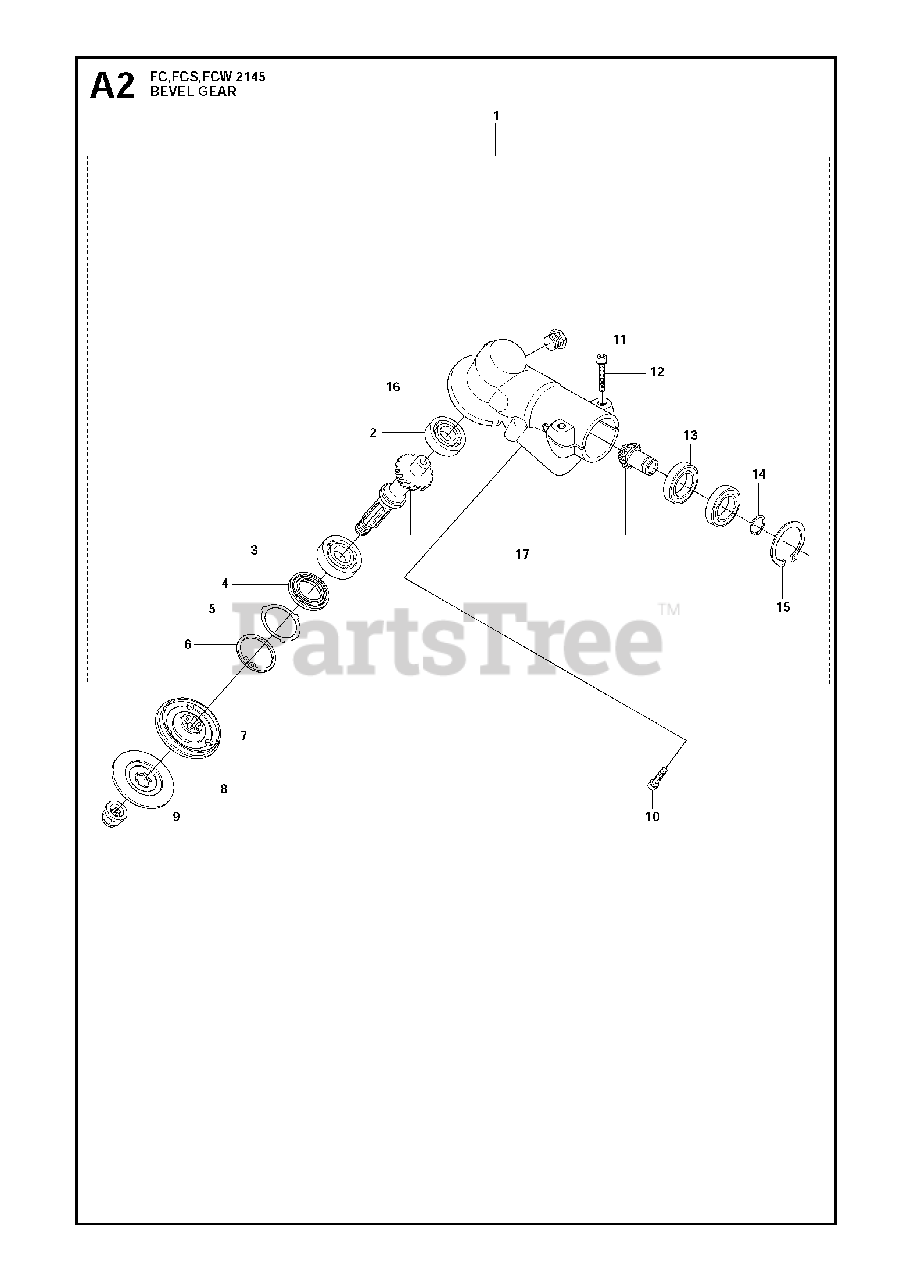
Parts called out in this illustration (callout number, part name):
1	GEAR HOUSING ASSY
2	BALL BEARING
3	BALL BEARING
4	SEAL
5	WASHER
6	RETAINING RING SGH 35
7	DRIVER
8	SUPPORT FLANGE
9	NUT BLADE
11	PLUG
12	SCREW
13	BALL BEARING
14	RETAINING RING SGA 15
15	RETAINING RING
16	GEAR HOUSING
17	SPARE PARTS KIT
